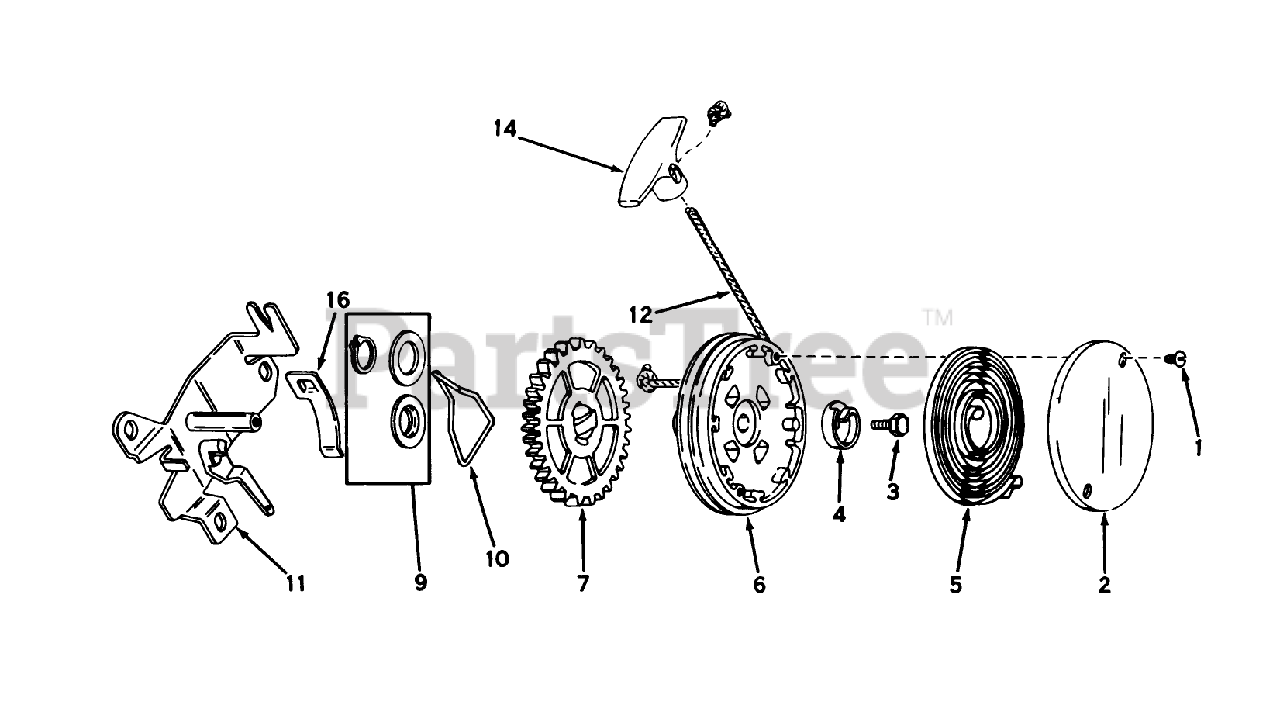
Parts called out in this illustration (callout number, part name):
1	Screw
2	Cover, Spring
3	Screw, Hex Washer Head
4	Hub Spring
5	Spring, Rewind
6	Pulley Assy. (Incl. No. 9)
9	Kit, Thrust Wash. Snap Rg.
10	Brake
11	Bracket Assy., Mounting
12	Rope-Starter
14	Handle-Starter
16	Clip Rope
